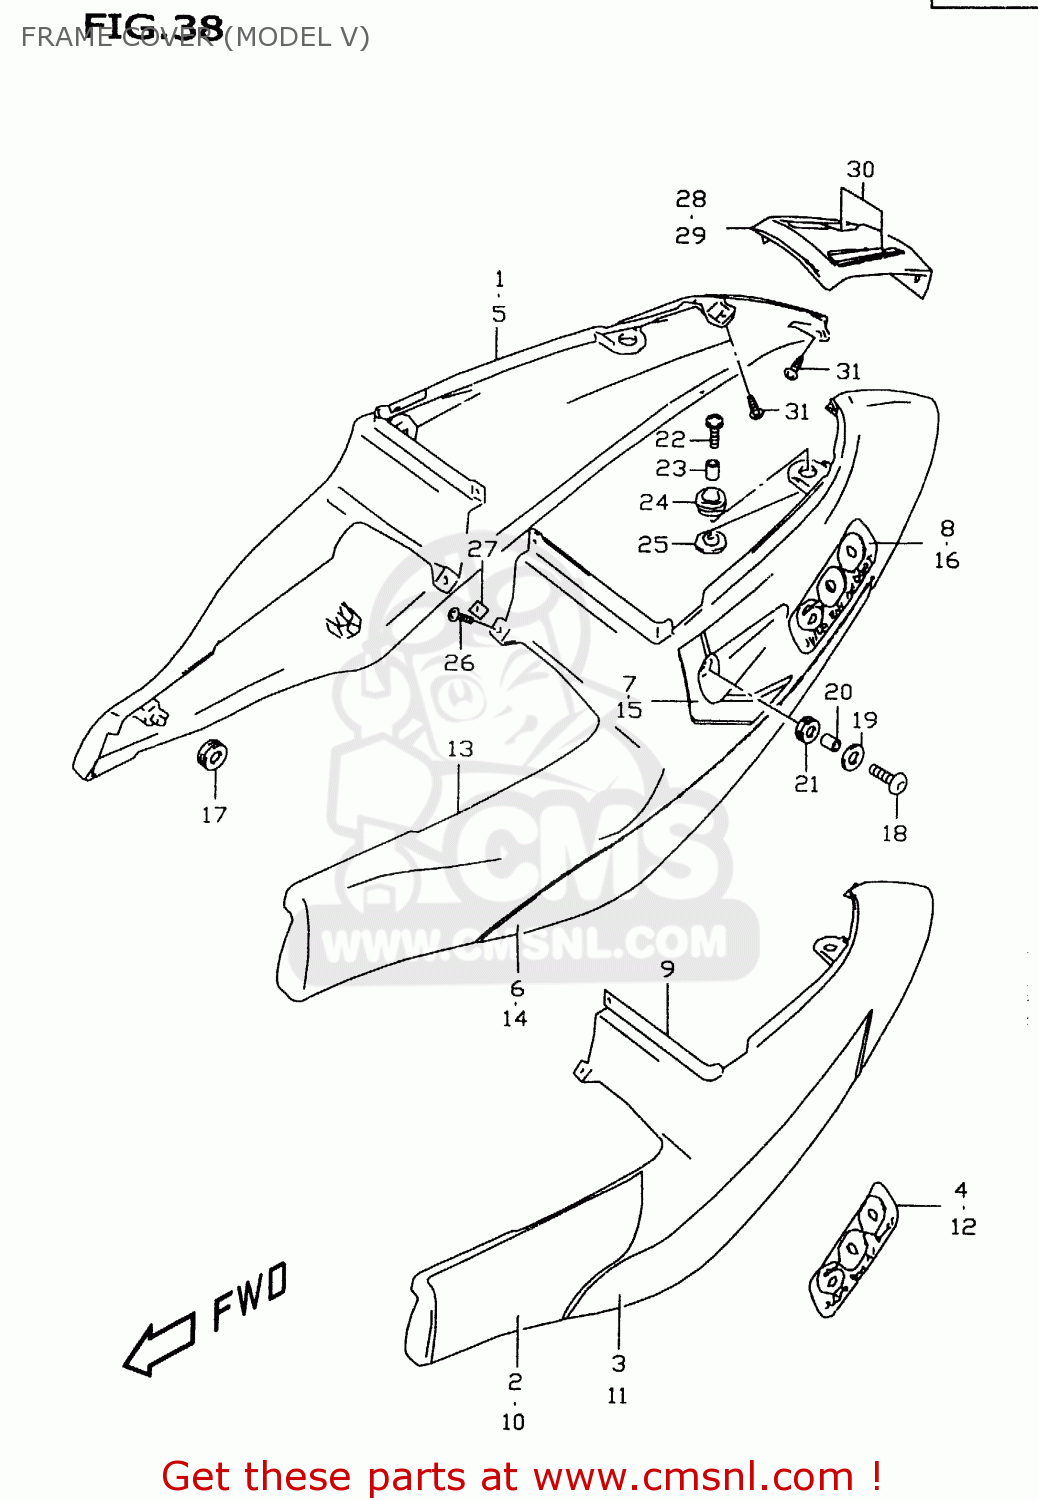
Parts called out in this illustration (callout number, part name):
1	COVER,FRAME,R(GRAY)
2	TAPE,FRAME COVER FR,R
3	TAPE,FRAME COVER RR,R
4	EMBLEM,FRAME COVER
5	COVER,FRAME,R(WHITE)
6	TAPE,FRAME COVER,R
7	TAPE,FRAME COVER STRIPE,R
8	EMBLEM,FRAME COVER
9	COVER,FRAME,L(GRAY)
10	TAPE,FRAME COVER FR,L
11	TAPE,FRAME COVER RR,L
12	EMBLEM,FRAME COVER
13	COVER,FRAME,L(WHITE)
14	TAPE,FRAME COVER,L
15	TAPE,FRAME COVER STRIPE,L
16	EMBLEM,FRAME COVER
17	CUSHION
18	SCREW(6X20)
19	WASHER(6.5X22X1.6)
20	SPACER(6.5X9X6.7)
21	CUSHION
22	SCREW(6X25)
23	SPACER(6.5X10X9.4)
24	CUSHION,TAIL COVER UPR
25	CUSHION,FRAME COVER LWR
26	SCREW
27	NUT
28	COVER,FRAME CTR
29	COVER COMP,FRAME,CENTER
30	TAPE SET,FRAME COVER CTR
31	SCREW
